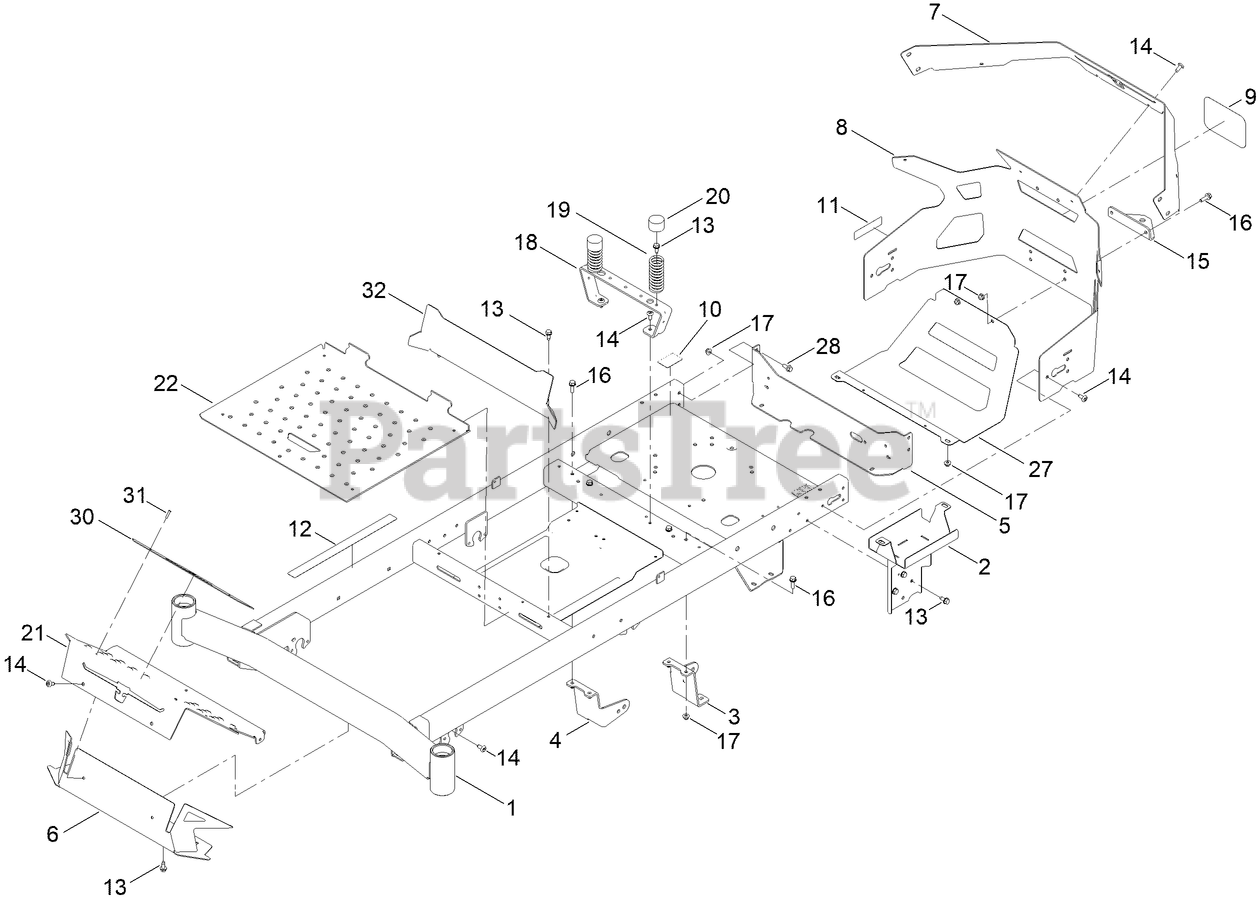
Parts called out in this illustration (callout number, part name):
1	SERVICE ASM-FRAME, TC
2	WA-BATTERY MOUNT
3	MOUNT-DRIVE, LH
4	MOUNT-DRIVE, RH
5	PLATE-MOUNT
6	FOOTREST-TOP
7	PLATE-REAR CLADDING TC
8	GUARD-ENGINE TC
9	DECAL
10	DECAL-BYPASS
11	DECAL-SPARK ARRESTER
12	DECAL-WARNING
13	SCREW-HWHTF
15	BRACKET-HITCH
16	SCREW-HHF
17	NUT-HF
18	SUPPORT-SEAT
19	SPRING-COMPRESSION
20	CAP-PROTECTOR
21	PLATE-KICK
22	PAN-FLOOR
27	GUARD-MUFFLER [BLACK]
28	SCREW-HHF
30	PLATE- TOEBOARD
31	RIVET-TRIFOLD
32	PLATE-KICK
